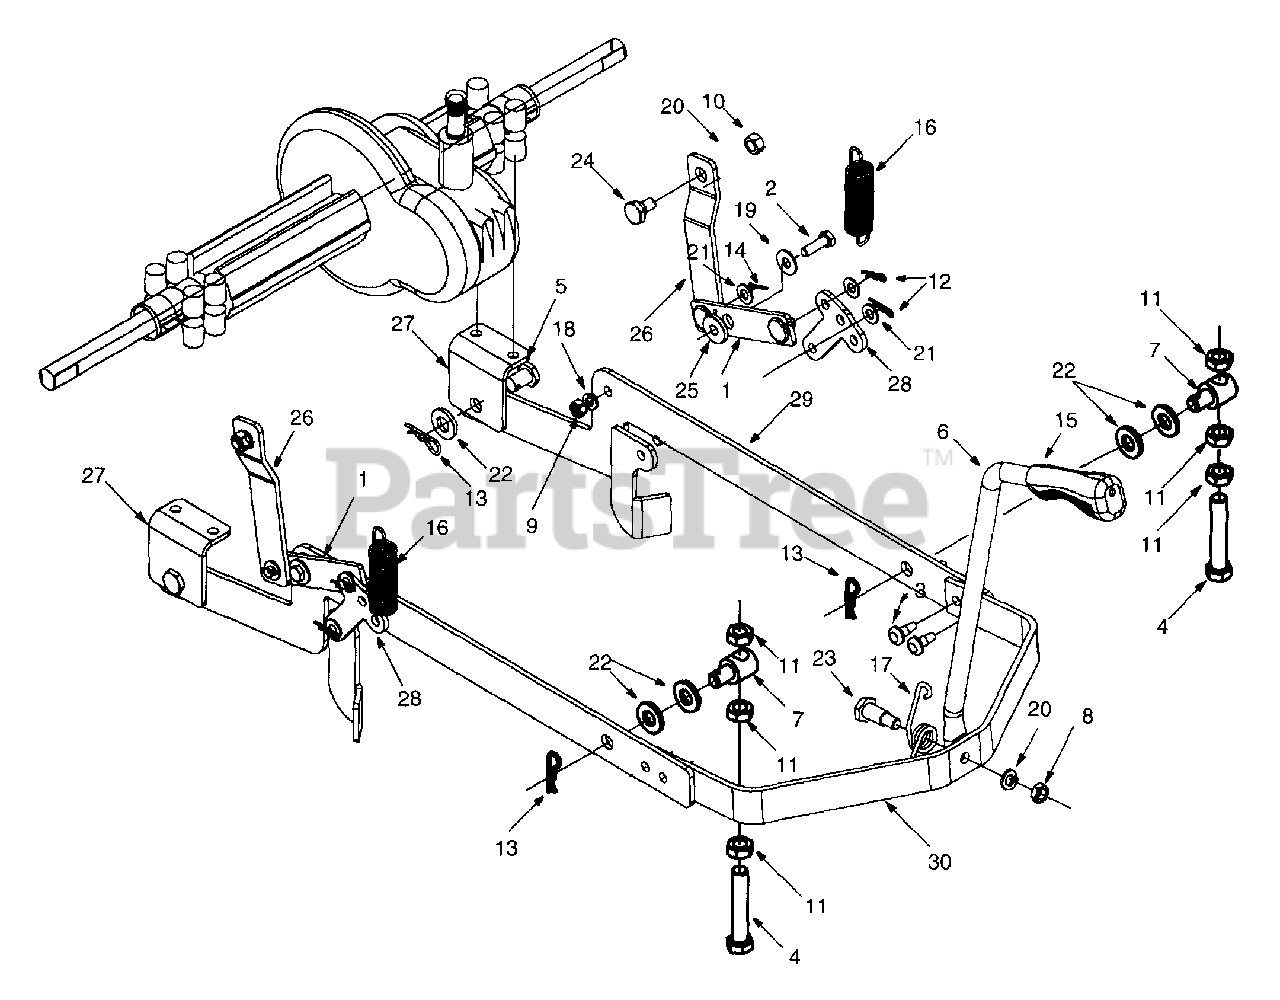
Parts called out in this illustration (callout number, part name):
4	Hex Bolt 1/2-13 X 2.75 Gr.5 Special
5	Lift Bracket Pin
6	Lift Rod
7	Ferrule
8	Jam Nut 3/8-16 Gr. 5
9	Hex Nut 5/16-18
10	Hex Cent. Lock Nut 3/8-16
11	Hex Jam Nut 1/2-13 Gr 5
12	Cotter Pin
13	Cotter Pin
14	Cotter Pin
15	Handle Grip
16	Extension Spring
17	Torsion Spring
18	Lock Washer 5/16
19	5/16 Washer
20	Lock Washer
21	Flat Washer 5/16
22	Flat Washer
23	Shoulder Screw
24	Shoulder Screw
25	Shoulder Spacer
